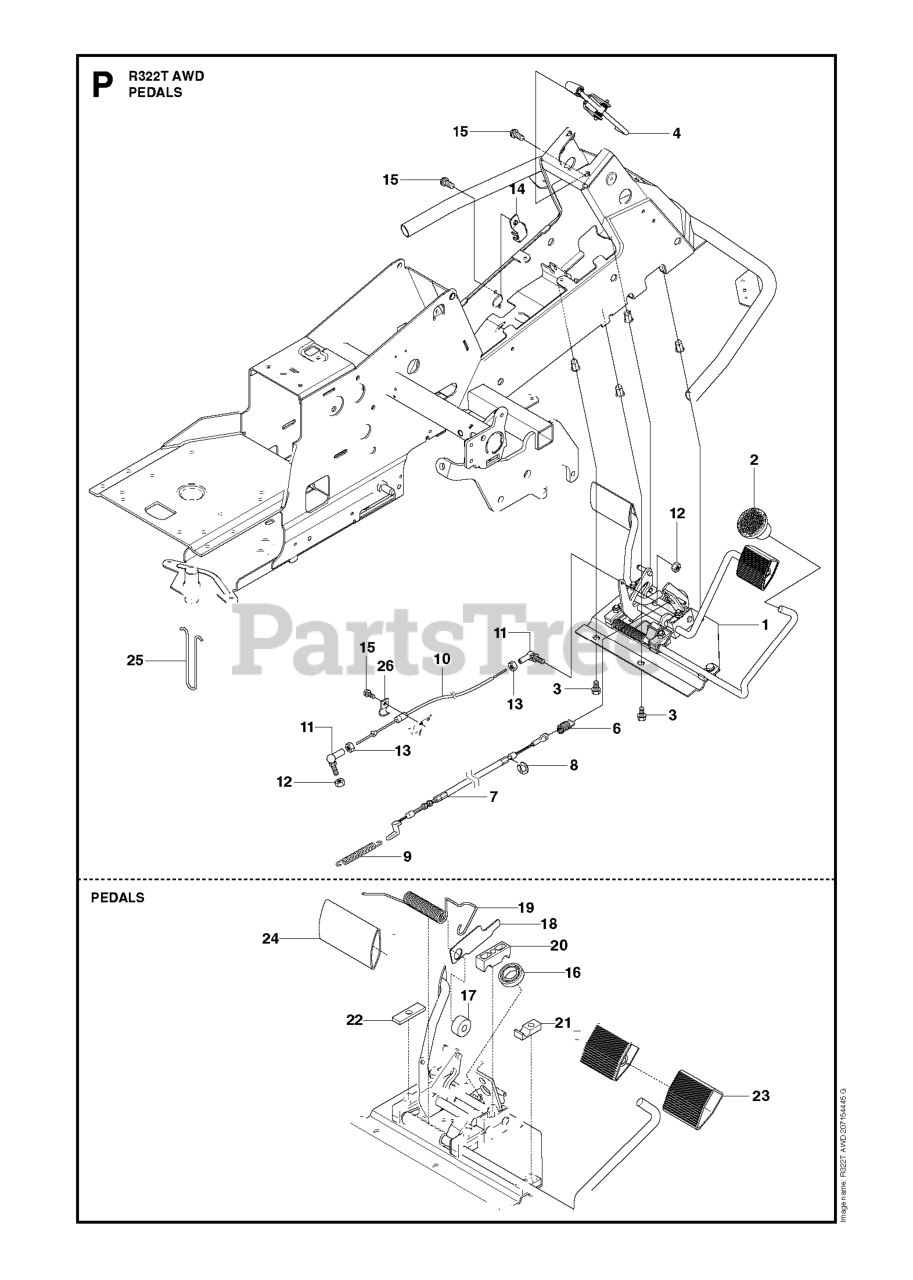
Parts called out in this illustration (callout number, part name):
1	PEDAL ASSEMBLY
2	KNOB
4	BRAKE LEVER ASSY
7	BRAKE WIRE
9	CONTROL CABLE
10	CONTROL CABLE
11	CONNECTOR
12	LOCKNUT M5
16	BALL BEARING 6002-2RS1
17	ROLLER
18	PLATE
19	SPRING
20	PEDAL SHAFT CLAMP
21	SUPPORT
22	PLATE
23	PEDAL RUBBER
24	PEDAL RUBBER, SF
25	CABLE HOLDER
